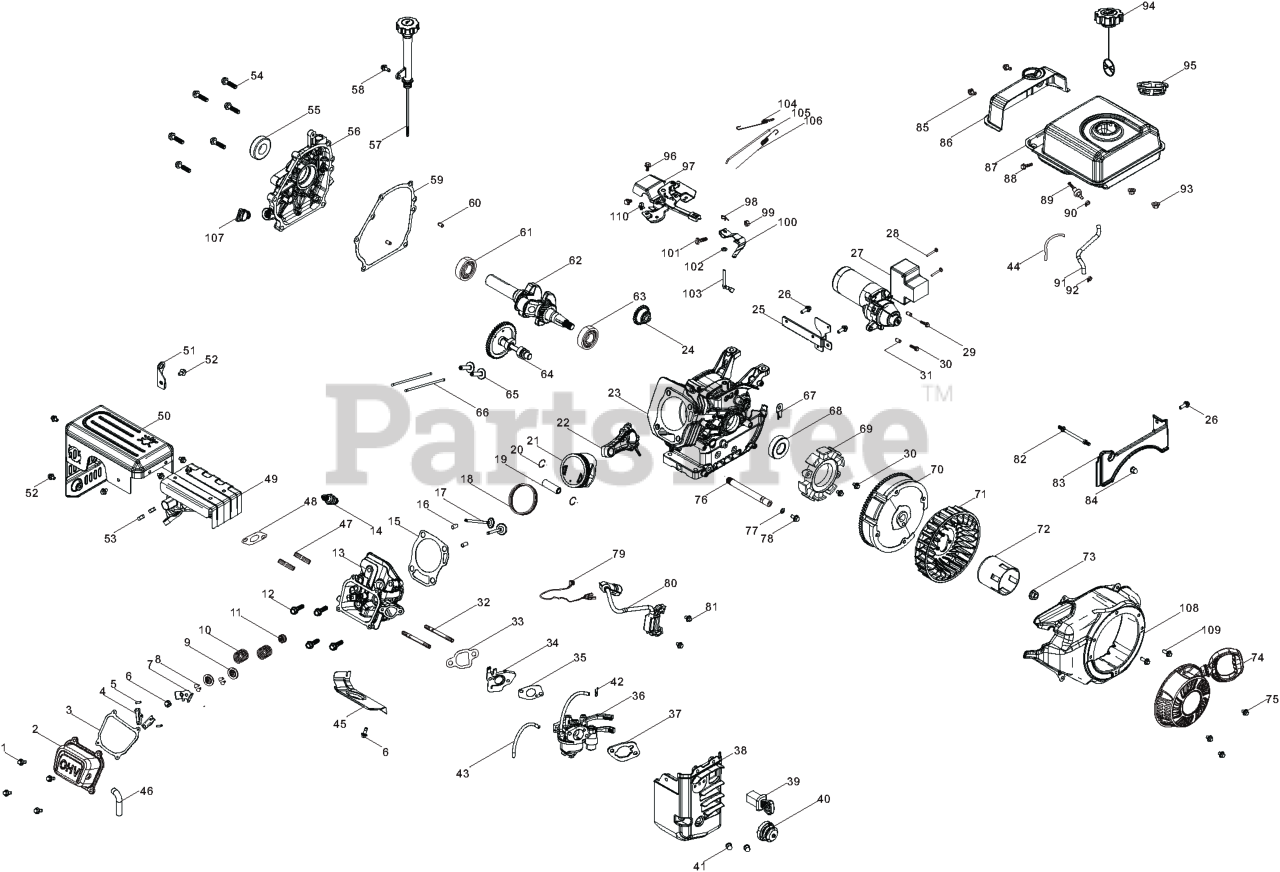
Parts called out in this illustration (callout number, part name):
1	BOLT, M6X12 HEX FLANGE
2	COVER, VALVE
3	GASKET, VALVE COVER
4	ROCKER SUBASSEMBLY, VALVE
5	ASM, ROCKER SHAFT
6	BOLT, M6X10 HEX FLANGE
7	CYL HEAD COVER PIN LIMIT PLATE
8	CLAMP, VALVE LOCK
9	SEAT, VALVE SPRING
10	SPRING, VALVE
11	GUIDE, SEAL
12	CYLINDER HEAD BOLT
13	ASM, CYLINDER HEAD
14	SPARK PLUG - PLATINUM
15	GASKET, CYLINDER HEAD
16	POSITION PIN - TYPE A
17	VALVES SET
18	RING ASSY, PISTON
19	PIN, PISTON
20	CLIP, PISTON PIN
21	PISTON
22	ROD, CONNECTING
23	CRANKCASE SUBASSEMBLY
24	GEAR ASSY, GOVERNOR
25	ASM,  CONTROL BOX SUPPORT
26	BOLT, M6X14 GRADE B HEX FLANGE
27	STARTING MOTOR ASSEMBLY
28	SCREW, PAN HEAD M4X55X0.7
29	BOLT, M6X35 HEX FLANGE
30	BOLT, M6X25 HEX FLANGE
31	POSITION PIN - TYPE A
32	STUD BOLT (BM=2D)
33	GASKET, CARBURETOR INSULATOR
34	PLATE, CARBURETOR INSULATOR
35	CARBURETOR SEAL GASKET
36	CARBURETOR ASSY
37	AIR CLEANER SEAL GASKET
38	BOX, HEATER
39	ASM, STOP ENGINE SWITCH
40	BULB, PRIMER
41	ACORN HEXAGON NUTS
43	LINE, PRIMER
44	JACKET, RUBBER
45	SHROUD, CYLINDER BODY
46	TUBE, BREATHER
47	STUD BOLT (BM=1.5D)
48	GASKET, EXHAUST OUTLET
49	MUFFLER ASSY
50	SHIELD, HEAT
51	TRANSPORT HANGER
52	BOLT, M6X12 HEX FLANGE
53	TYPE 1 HEXAGON NUT
54	BOLT, M8X32 HEX FLANGE
55	SEAL, OIL
56	COVER, CRANKCASE
57	DIPSTICK SUBASSEMBLY, OIL
58	BOLT, M6X16 HEX FLANGE
59	GASKET, CRANKCASE
60	POSITION PIN - TYPE A
61	BRG, P53 DEEP GROOVE BALL
62	CRANKSHAFT ASSY
63	BRG, P53 DEEP GROOVE BALL
64	CAMSHAFT ASSY
65	TAPPET, VALVE
66	LIFTER, VALVE
67	CLAMP, HARNESS
68	SEAL, OIL
69	COIL SUBASSEMBLY, CHARGE
70	FLYWHEEL SUBASSEMBLY
71	IMPELLER
72	CUP, STARTER
73	NUT, FLYWHEEL
74	RECOIL, MANUAL STARTER
75	BOLT, M6X12 GRADE B HEX FLANGE
76	TUBE, OIL DRAIN
77	FLAT WASHER - GRADE A
78	BOLT, DRAIN PLUG
79	WIRE, IGNITION COIL STOP ENG
80	COIL, IGNITION
81	BOLT, M6X25 HEX FLANGE
82	STUD BOLT (BM=2D)
83	FRONT SNOW GUARD
84	ACORN HEXAGON NUTS
85	BOLT, M6X12 HEX FLANGE
86	FUEL TANK PLATE
87	FUEL TANK
88	BLT, M6X32 HEX FLANGE
89	OUTLET WITH FILTER
90	PIPE CLAMP
91	TUBE, FUEL
92	PIPE CLAMP
93	HEXAGON NUT WITH FLANGE
94	CAP, FUEL
95	FUEL GAUGE
96	BOLT, M6X10 HEX FLANGE
97	CONTROL ASSY, THROTTLE
98	COTTER PIN
99	HEXAGON NUT WITH FLANGE
100	ASM, GOVERNOR BRACKET
101	BOLT, GOVERNOR SUPPORT
102	FLAT WASHER - GRADE A
103	ARM, GOVERNOR
104	SPRING, GOVERNOR
105	ROD, GOVERNEOR
106	SPRING, THROTTLE VLV RETURNING
107	ASM, ENGINE OIL PLUG
109	BOLT, M6X12 GRADE B HEX FLANGE
NS	KIT,252CC 3000-6000FT CARB JET
NS	KIT,252CC 6000-8000FT CARB JET
